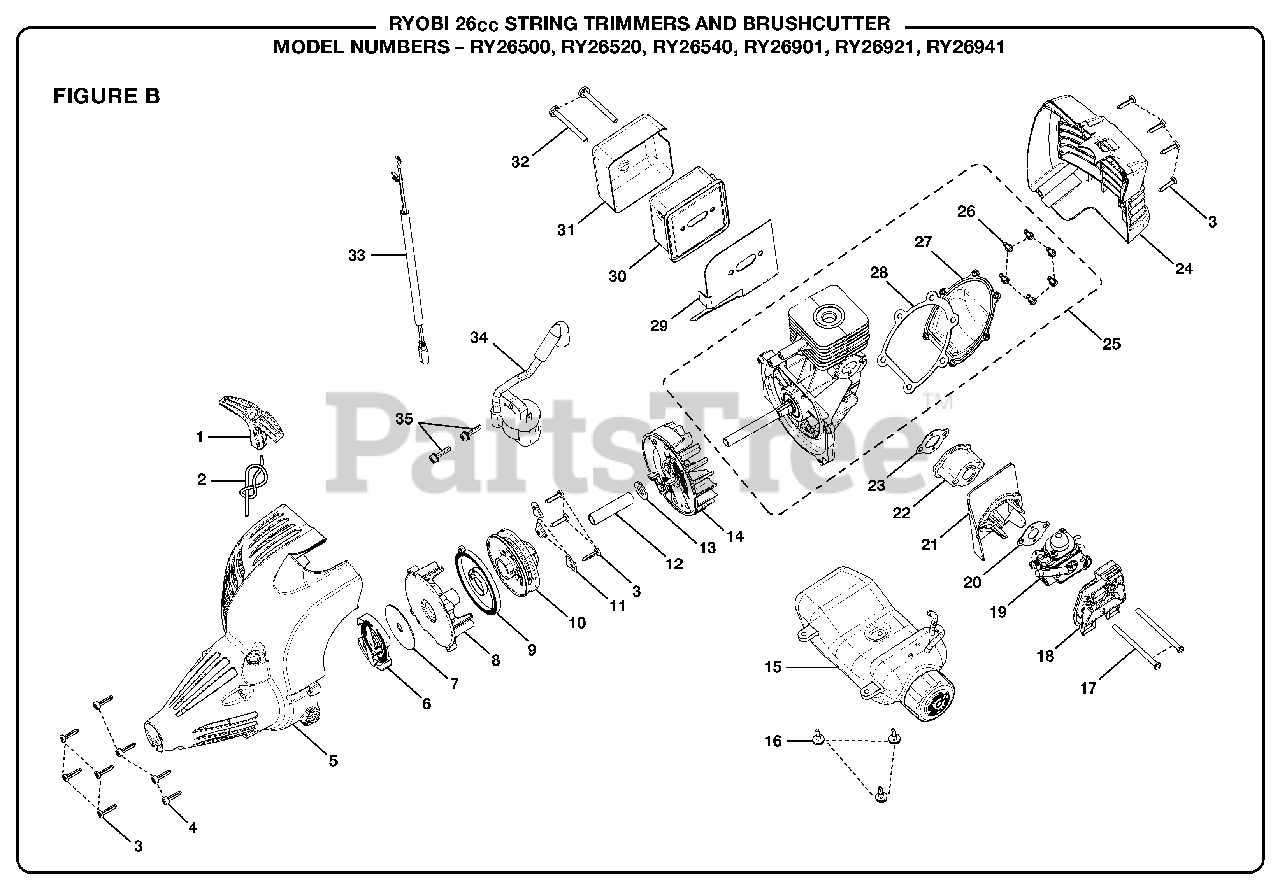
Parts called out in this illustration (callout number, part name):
1	Starter Grip
2	Starter Rope
3	Screw (M4 x 18 mm)
4	Screw (M4 x 16 mm)
5	Starter Housing Assembly
6	Clutch Assembly
8	Starter Baffle
9	Spring and Container
10	Easy Starter Assembly
11	Pulley Retainer
12	Spacer Tube
13	Washer
14	Flywheel Assembly
15	Fuel Tank and Cap Assembly
16	Screw (M4)
17	Bolt (M5 x 70 mm)
18	Air Box Base
19	Carburetor Assembly
20	Outer Heat Dam Gasket
21	Air Baffle
23	Inner Heat Dam Gasket
24	Rear Housing
25	Short Block Assembly
26	Screw (M4 x 12 mm)
27	Crankcase Cover
28	Crankcase Cover Gasket
29	Muffler Gasket
30	Muffler Assembly
31	Muffler Housing
32	Muffler Bolt (10-24 x 2-1/8 in.)
33	Electrical Lead Wire Assembly
34	Ignition Module
35	Screw (M4 x 19 mm)
